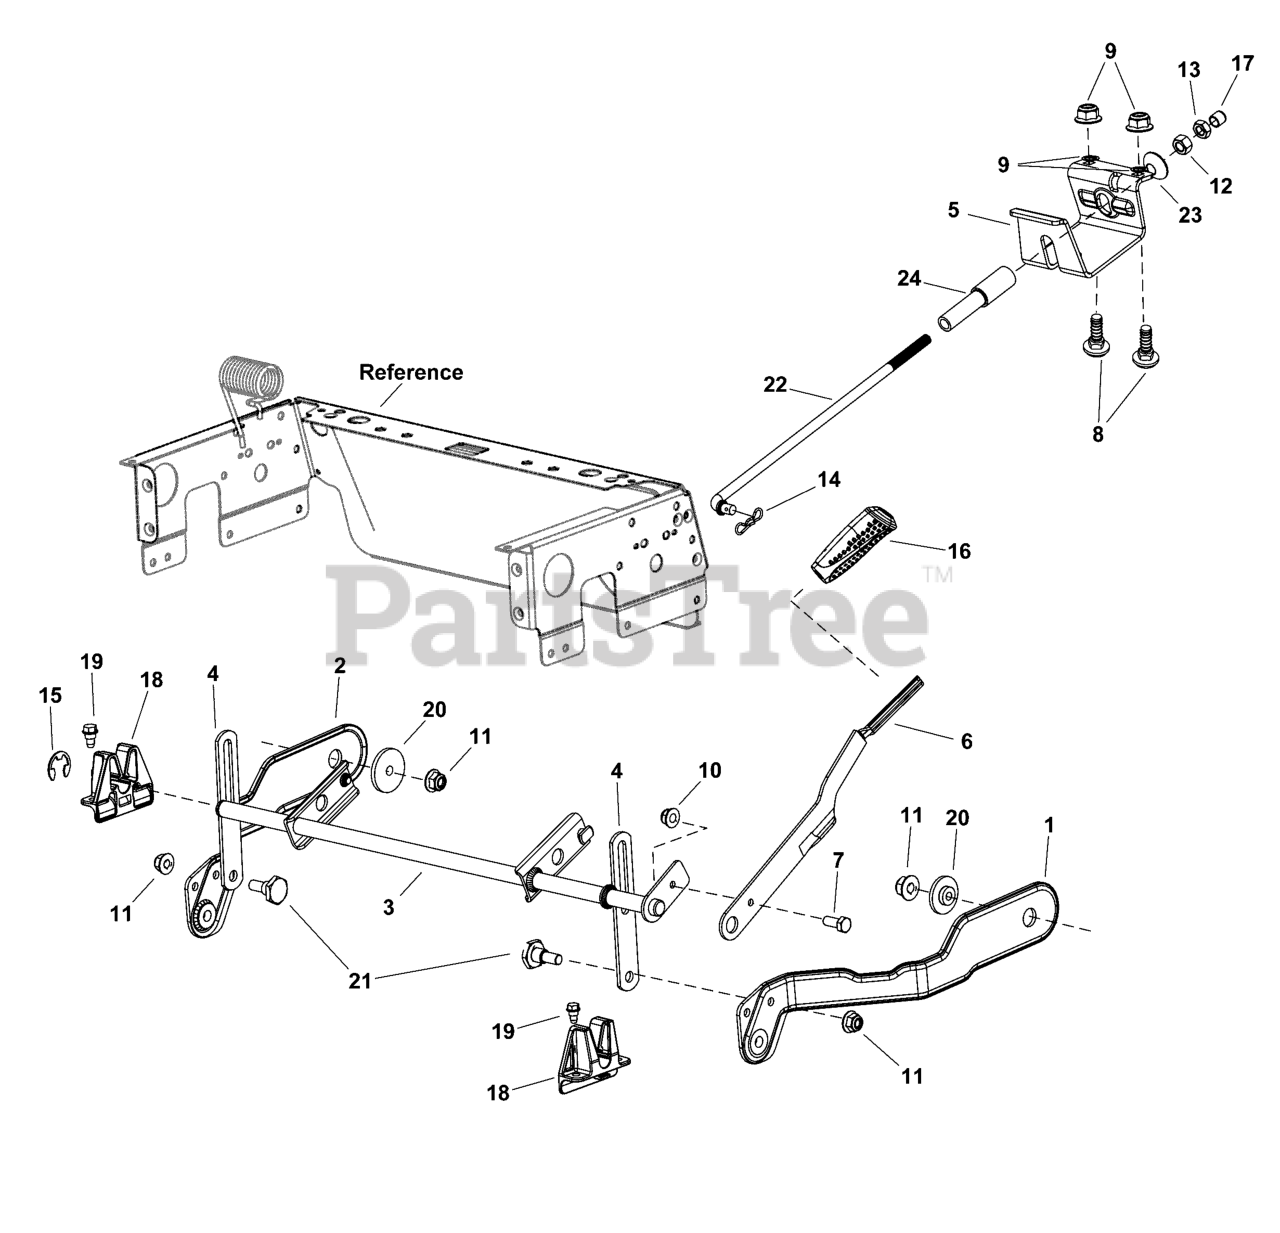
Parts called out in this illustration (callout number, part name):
1	PLATE, Deck Lift, RH
2	PLATE, Deck Lift, LH
3	ASSEMBLY, Deck Lift Shift
4	PLATE, Lift Link
5	BRACKET, Rod Support Mounting
6	HANDLE, Deck Lift
7	SCREW, 5/16-18 X .75, Hex Cap
8	BOLT, 3/8-16 X 1.00, Carriage
9	NUT, 3/8, Push
11	NUT, 3/8-16, Flanged Lock, GR5
12	NUT, 1/2-13, Hex Nylock
13	NUT, 1/2-13, Hex
14	PIN, Bow Tie Cotter
17	END CAP, Lift Rod
18	BRACKET, Deck Lift
19	BOLT, Shoulder, 1/4-20 x 1/2"
20	SPACER, Shoulder -S
21	SCREW, 3/8-16, Shoulder
22	ROD, Deck Front Lift
23	CUP, Lift Pivot
24	SLEEVE, .55 ID X 4.50 LG
